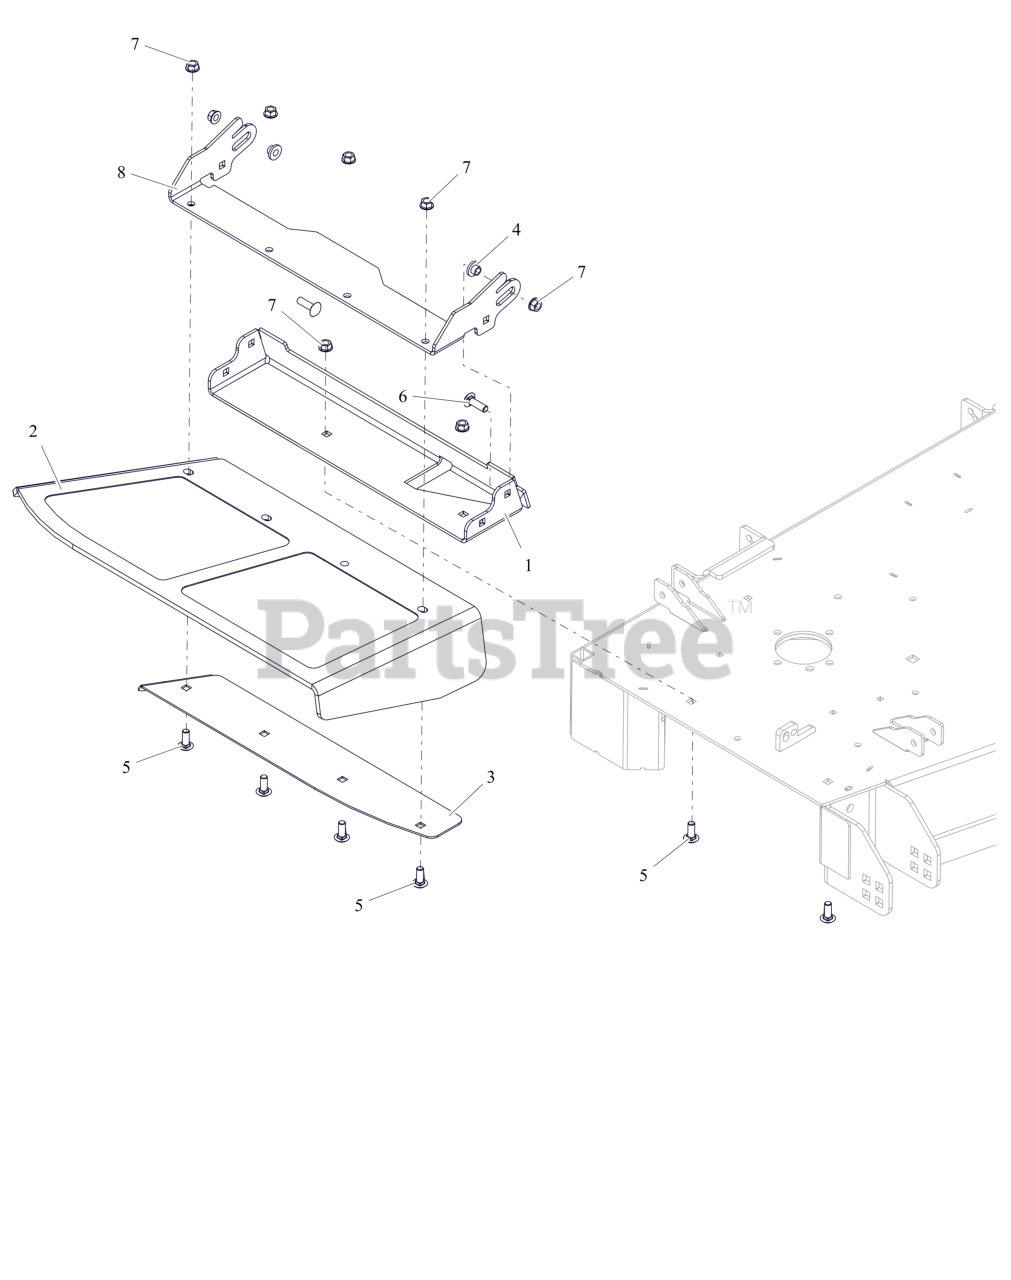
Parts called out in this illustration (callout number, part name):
1	BRKT- DISCHARGE CHUTE MTG
2	CHUTE, 72" FORMED RUBBER DISCH
3	72" DISCH CHUTE CLAMP PLT -RED
4	BSHG-FLG .385X.500X.875X.406
5	BLT,RHSSN .38-16X1.00 G5 ZCC
6	BLT,RHSSN .38-16X1.25 G5 ZCC
7	NUT-LK-CTR-FLG .375-16 GF ZCC
8	BRKT, CHUTE MTG (RED)
